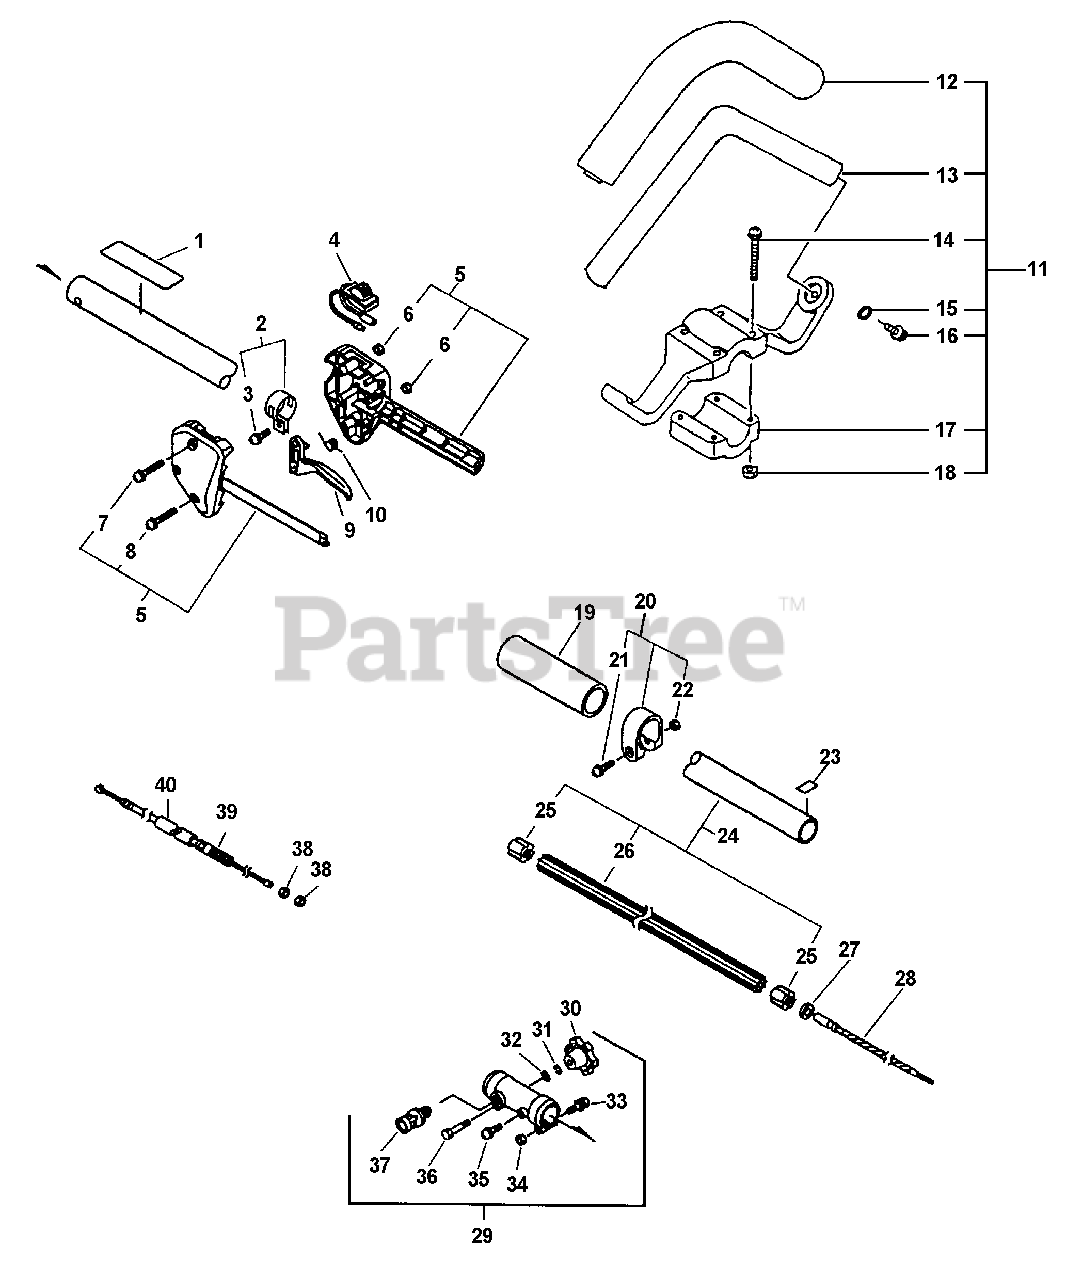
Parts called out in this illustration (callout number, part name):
1	LABEL, CAUTION
2	CLAMP KIT
3	SCREW 5×14
4	SWITCH ASSY, ON-OFF
5	HANDLE KIT, CONTROL
6	NUT M5
7	SCREW 5×35
8	SCREW 5×25
9	TRIGGER, THROTTLE
10	SPRING, TORSION
11	FRONT HANDLE ASSY
12	GRIP, HANDLE
13	HANDLE, SUPPORT
14	SCREW 5×35
15	WASHER, FLAT 5.5×10×0.8
17	BRACKET, HANDLE - LOWER
18	NUT M5
19	GRIP, HANDLE
20	CLAMP KIT
21	SCREW 5×28
22	NUT M5
23	LABEL - ALIGNMENT
24	MAIN PIPE ASSY
26	LINER - FLEXIBLE
28	DRIVESHAFT - FLEXIBLE
29	COUPLER ASSY
30	KNOB, FASTENER
31	WASHER, SPRING 5
32	WASHER, FLAT 5.5×10×0.8
33	BOLT 5×30
34	NUT M5
35	SCREW 5×12
36	BOLT 5×35 SP
37	LATCH ASSY
39	CABLE, THROTTLE
40	TUBE
